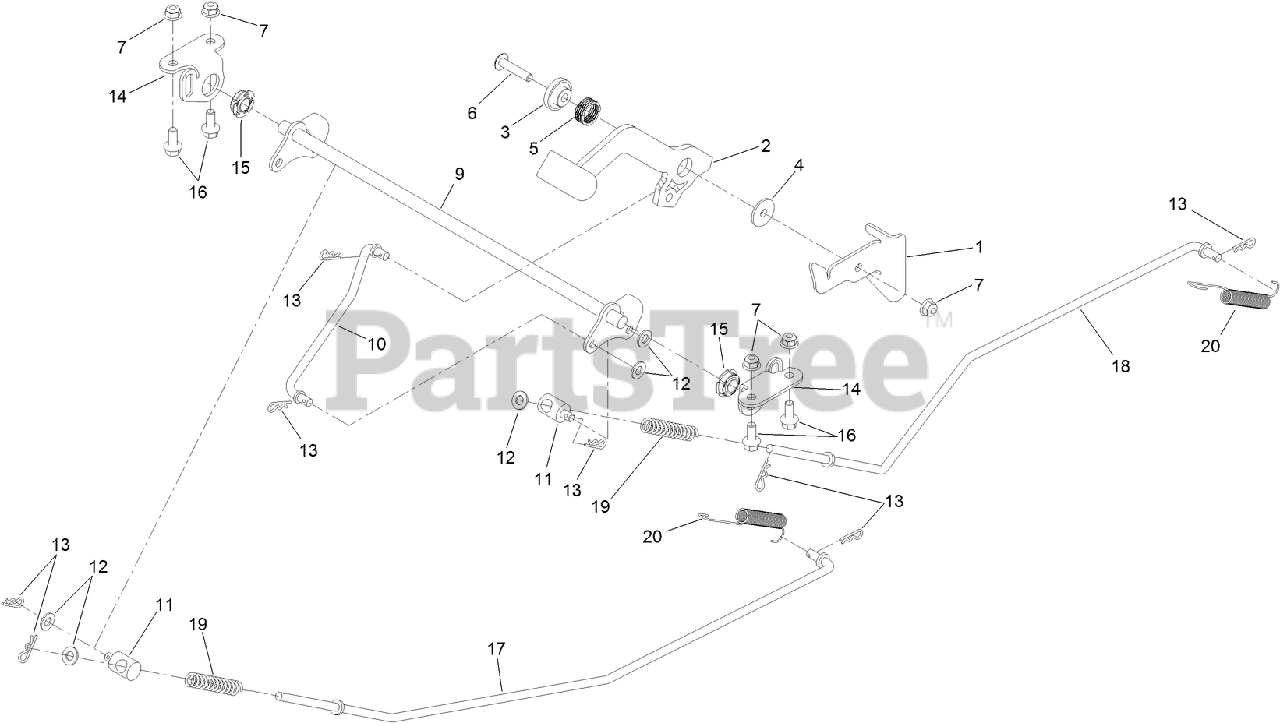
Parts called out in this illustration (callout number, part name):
1	DETENT-BRAKE
2	LEVER-BRAKE
3	BUSHING-FLANGE
4	BUSHING-BRAKE, FLANGED
5	SPRING-WAVE
6	SCREW-TORX
7	NUT-HF, NI
9	BELLCRANK-BRAKE
10	ROD-BRAKE, INTERMEDIATE
11	FITTING-ROD
12	WASHER-PLAIN
14	PLATE-SUPPORT, BELLCRANK
15	BEARING-SPHERICAL
16	SCREW-HHF
17	ROD-BRAKE, RH
18	ROD-BRAKE, LH
19	SPRING-RETURN, NEUTRAL
20	SPRING-EXTENSION
